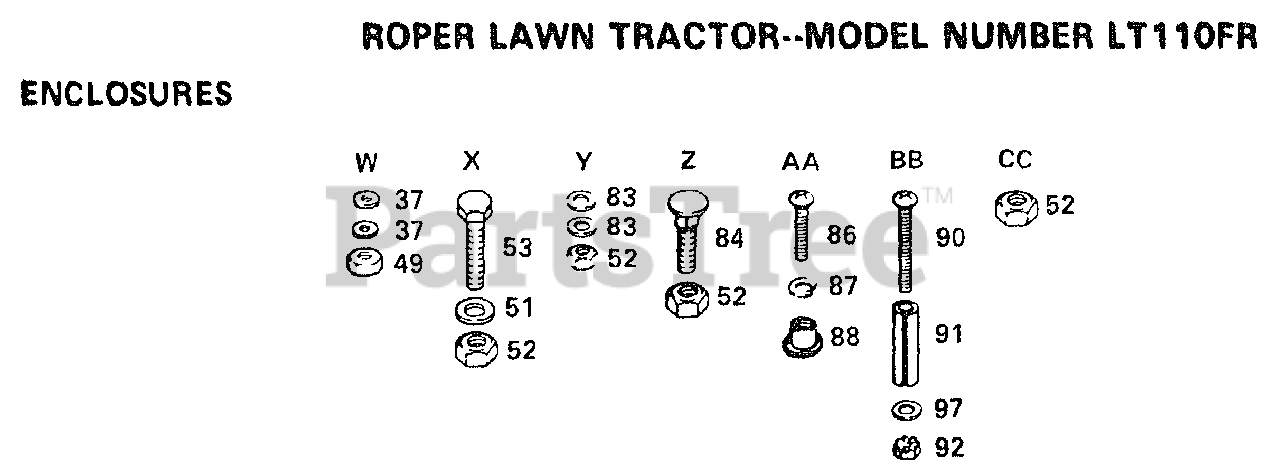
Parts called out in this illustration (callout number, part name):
37	WASHER PM
51	WASHER
53	BOLT
83	WASHER
84	BOLT
86	SCREW
87	LOCKWASHER
88	WELDNUT
90	SCREW
91	SPACER LT
97	WASHER
